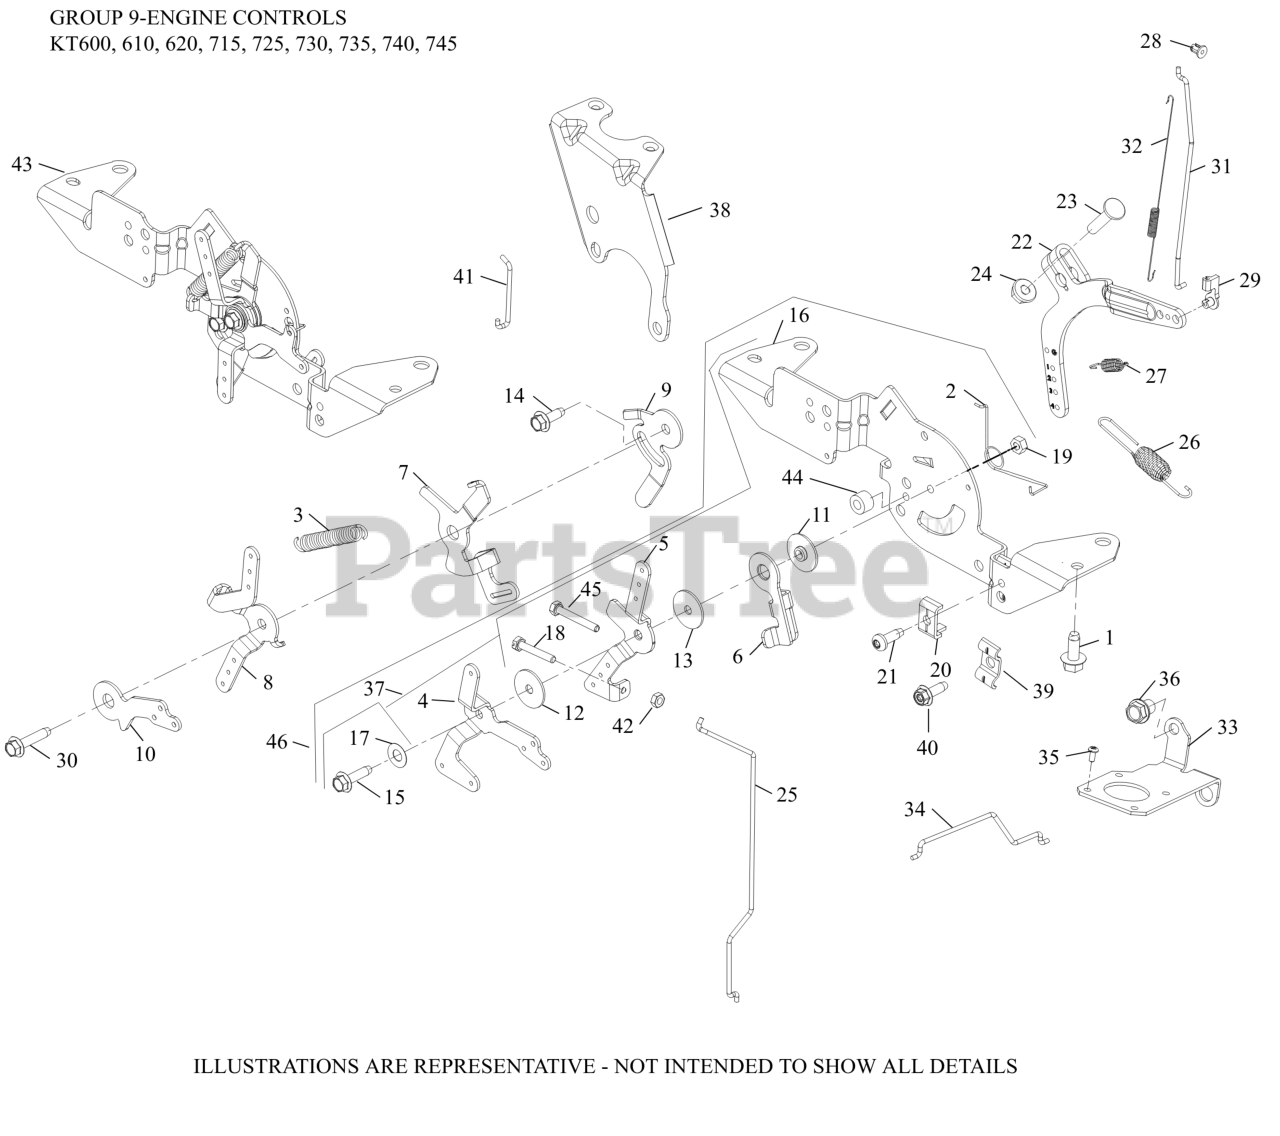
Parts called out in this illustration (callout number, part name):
1	SCREW, THREAD FORMING
20	CLAMP, CABLE-(#2523753S)
22	LEVER, GOVERNOR - (#2409069S)
23	BOLT, RD HD SQ NECK M6X1.0X25
24	NUT, FLG M6X1.0
25	LINKAGE, CHOKE
26	SPRING, GOVERNOR (ORANGE)
27	SPRING, GOVERNED IDLE
28	BUSHING, LINKAGE RETAINING
29	BUSHING, THROTTLE LINKAGE
32	SPRING, LINKAGE
34	LINKAGE, THROTTLE
40	SCREW, THREAD FORMING
